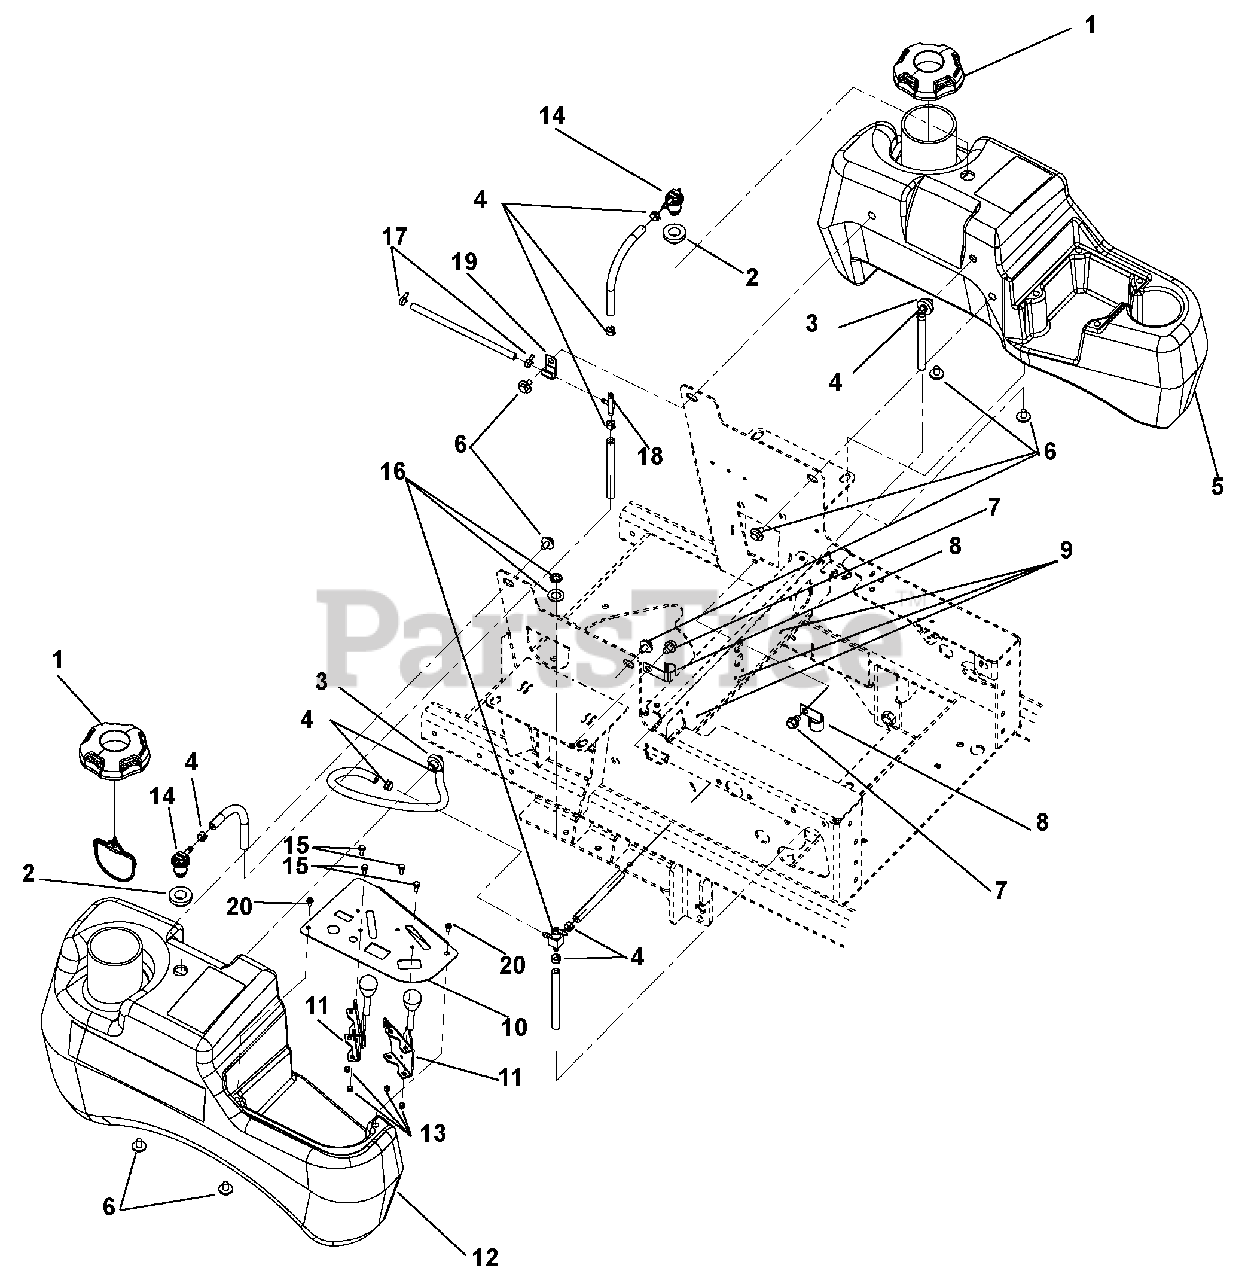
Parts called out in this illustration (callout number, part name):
1	Cap, 3.50" Vent-in Ratchet Fuel
2	Grommet, Remote Vent Nitrile
3	Assembly, Medium Tank Fuel Pick-up
4	Clamp, Fuel Line
5	Tank, LH Medium Gravely Fuel (991300 SN 002500 – 004999, 991303 SN 000101 – 004999)
6	Bolt, SEMS .31-18 x .62
7	Screw, Tapping .38-16 x .50 Hex Washer Head Thread Rolling
9	Cable Tie
10	PT100 Control Panel, Black
11	Cable, PT100 Throttle Control
12	Tank, RH Medium Gravely Fuel (991300 SN 002500 – 004999, 991303 SN 000101 – 004999)
13	Nut, Locking, Nylon 10-24 w/Insert
14	Valve, Combination
15	Screw, Machine 10-24 x .50 Hex Washer Head
16	Valve, Fuel
17	Clamp, Hose, Spring .188
18	Tee, 1/4HS Run x 3/16HS Branch
20	Screw, Machine 10-24 x .38 HWH Stainless
